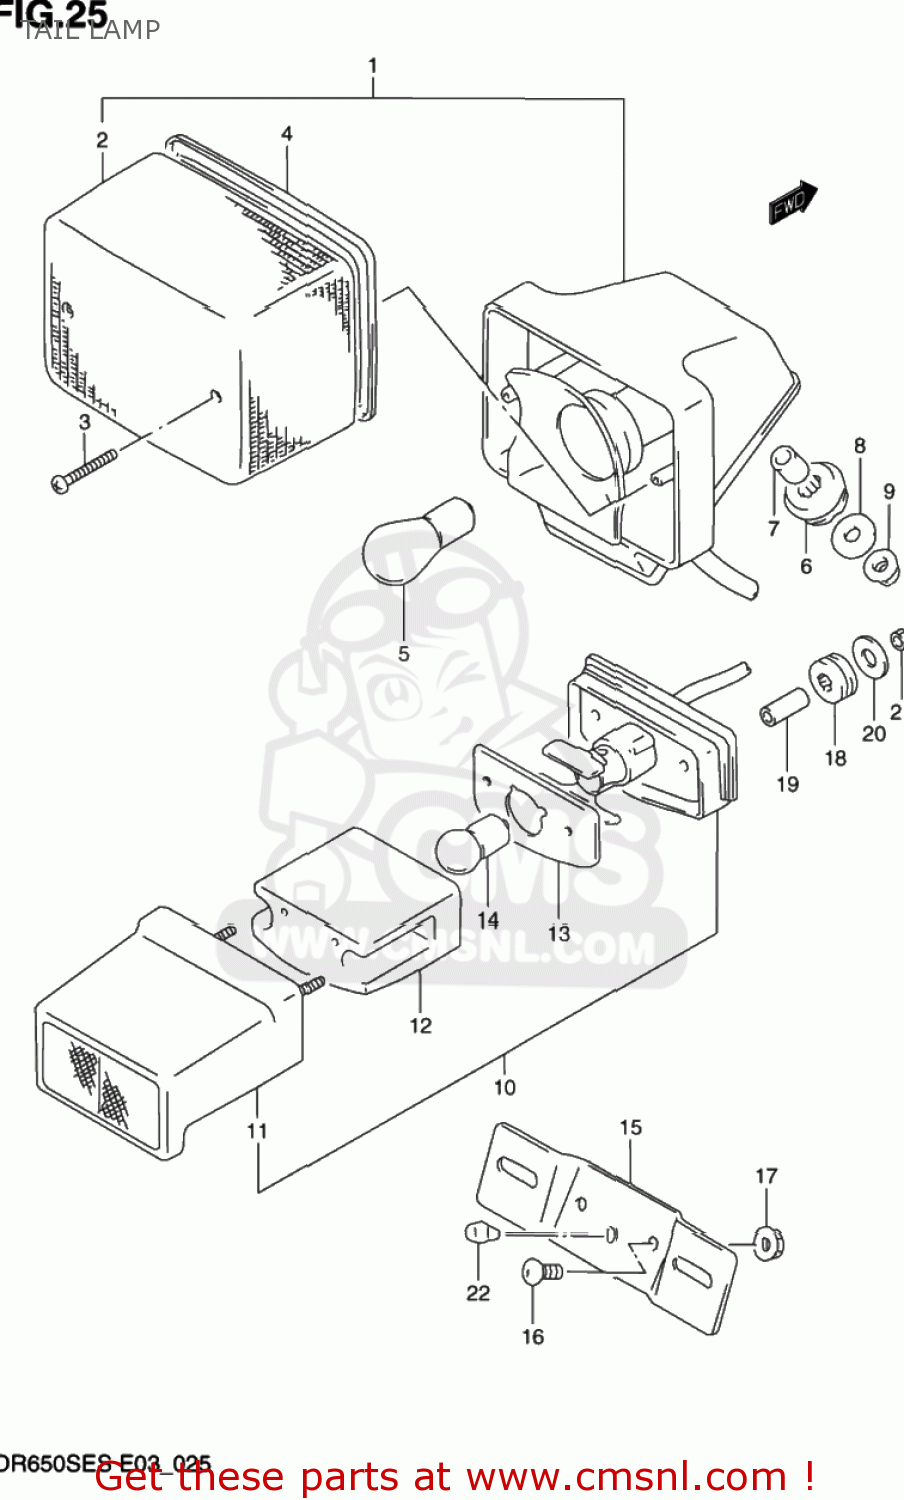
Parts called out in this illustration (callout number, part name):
1	LAMP ASSY,RR COMBINATION
2	LENS,TAIL LAMP
3	SCREW(4X45)
4	GASKET,LENS (NAS)
5	BULB(12V21/5W)
6	CUSHION
7	SPACER (6.1X9X9)
8	WASHER(6.5X20X1.6)
9	NUT
10	LAMP ASSY,LICENSE
11	REFLECTOR/COVER
12	LENS
13	GASKET,LICENSE LAMP (NAS)
14	BULB
15	BRACKET,LICENSE PLATE
16	SCREW
17	NUT
18	CUSHION
19	SPACER,LICENSE LAMP
20	WASHER(5.5X20X1.2)
21	NUT
22	CUSHION
